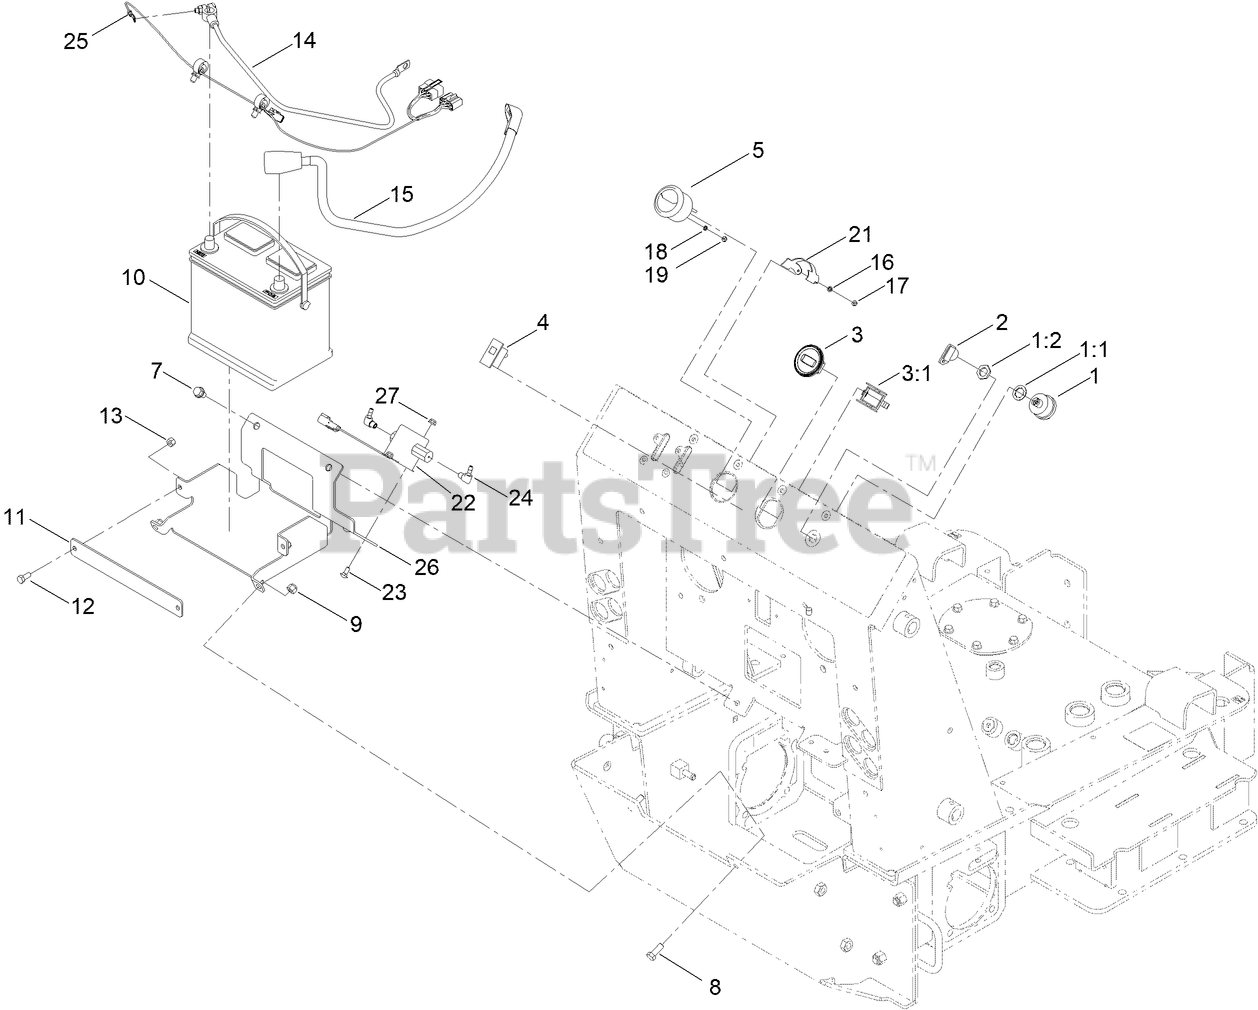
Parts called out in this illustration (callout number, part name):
1:1	WASHER-LOCK
1:2	NUT-HH
2	KEY-IGNITION
3	INDUCTIVE HOURMETER ASM
3:1	CLIP-MOUNTING
4	LIGHT-TEMP, OIL
5	GAUGE-FUEL
7	SCREW-HWHTF
8	SCREW-HH
9	NUT-LOCK, NI
11	CLAMP-BATTERY
12	SCREW-HH
13	NUT-LOCK, NI
14	CABLE-BATTERY, NEGATIVE
15	CABLE-BATTERY, POSITIVE
16	WASHER-LOCK,#8
17	NUT-HEX,#8
18	WASHER-LOCK,#6
19	NUT-HEX,#6
21	BRACKET-MOUNTING, GAUGE
22	PUMP - FUEL: FACET W/ CONNECTOR
23	SCREW-CARR
24	ELBOW-90 DEG, BARBED
25	HARNESS-WIRE, HIGH ALTITUDE FUEL PUMP
26	TRAY-MOUNTING, BATTERY
27	NUT-HF
